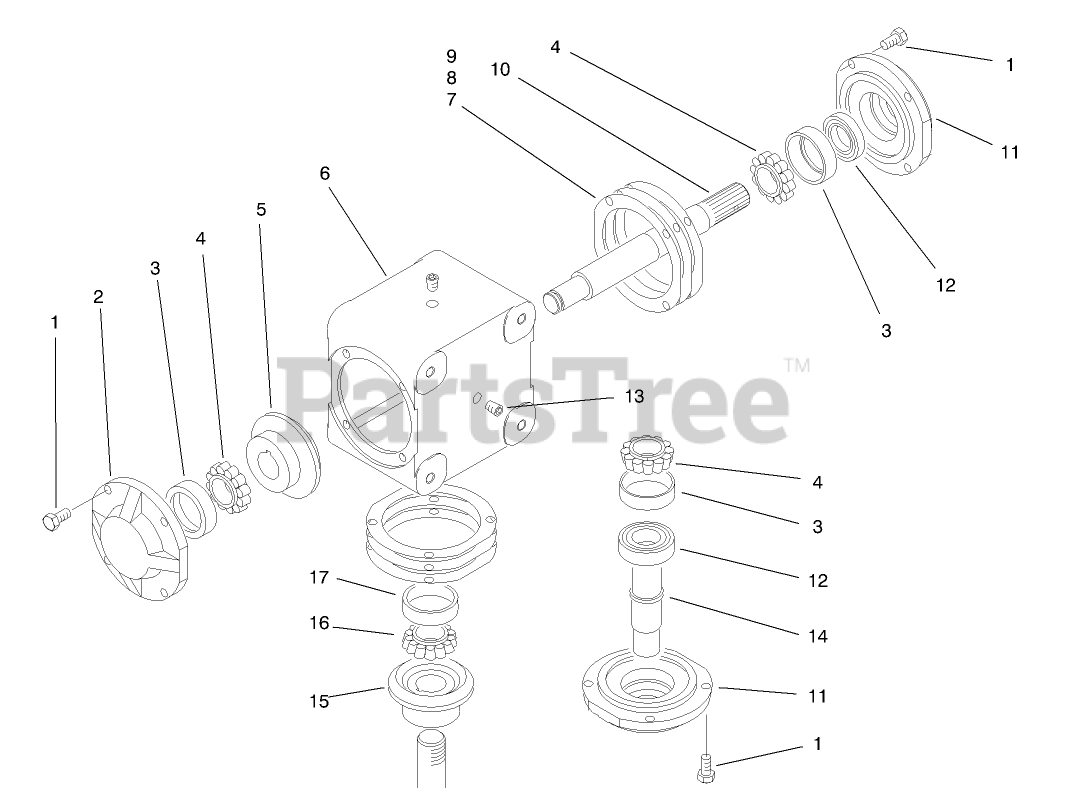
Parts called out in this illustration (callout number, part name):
1	SCREW
3	Cup
4	BEARING - CONE
5	GEAR LH
6	HOUSING
7	GASKET
8	GASKET
9	GASKET
10	SHAFT
11	Cap
12	Seal
13	PLUG (OBS, C/R TO 281-10)
14	SHAFT
15	GEAR RH
16	Cone
17	Bearing Cup
